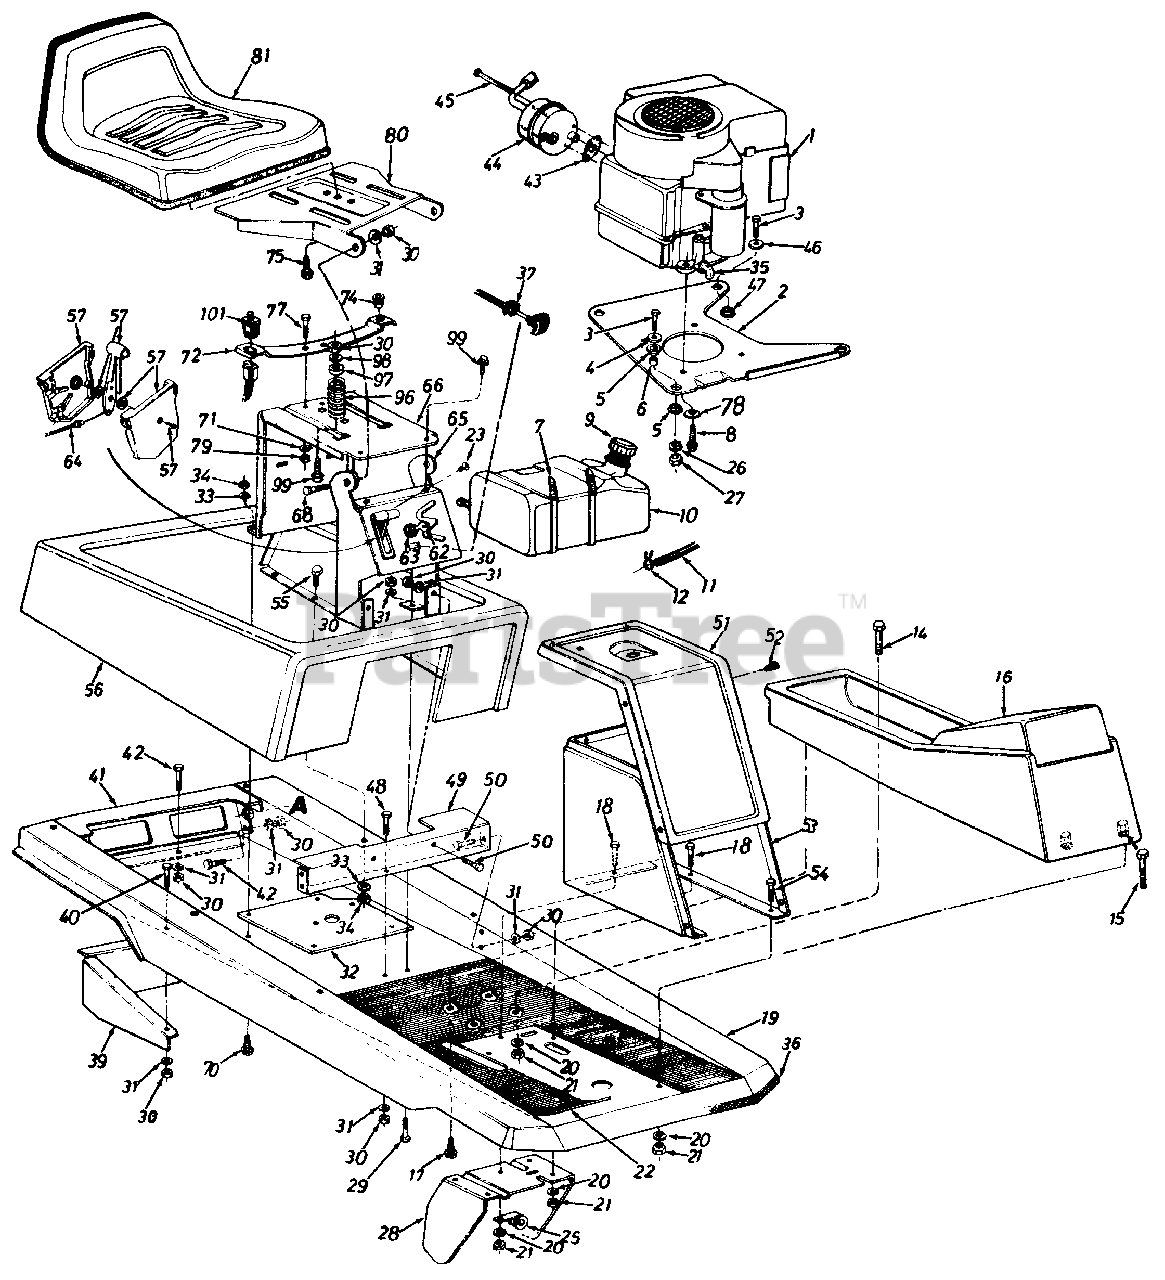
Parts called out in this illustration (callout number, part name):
1	Engine
4	Fl-Wash. .330" I.D. x 1.125" O.D.
5	Engine Mounting Grommet
6	Spacer .315" I.D. x .50" O.D. x .520" Lg.
7	Cable Tie 30.6 Lg.
8	Hex Wash. Hd. Self-Tap Scr. 3/8-16 x 1.25" Lg.
9	Gas Cap
10	Fuel Tank
11	Fuel Line - 26" Lg.
12	Hose Clamp - 1/2" O.D. Tube
14	Hex Bolt 5/16-18 x 1.75" Lg.
15	Hex Bolt 5/16-18 x 2" Lg.
16	Front Console
17	Plastite Scr. 5/16 x 1.25" Lg.
18	Hex Bolt 5/16-18 x .75" Lg.
19	Main Frame
20	L-Wash. 5/16" I.D.
21	Hex Nut 5/16-18 Thd.
22	Floor Mat
23	Truss Mach. Ab-Tap Scr. #10 x .50" Lg.
25	Clamp
26	L-Wash. 5/16" I.D.
27	Hex Nut 5/16-24 Thd.
28	Clutch-Brake Pedal Ass'y.
29	Hex Bolt 5/16-18 x .75" Lg
30	Hex Nut 5/16-18 Thd.
31	L-Wash. 5/16" I.D.
34	Hex Nut 1/4-20 Thd.
35	90ø Elbow Male To Female
36	Trim Strip (39" Req'd.)
37	Choke Control
43	Exhaust Gasket (8 H.P. B&S)
44	Muffler Ass'y. (8 H.P. B&S)
45	Shld. Bolt (8 H.P. B&S)
46	Fl-Wash. .330" I.D. x 1.25" O.D.
47	Flange Wash. .320" I.D. x .750" O.D.
49	Seat Support & Frame Brkt.
50	Hex Bolt 5/16-18 x .75" Lg.
55	Hex Bolt 1/4-20 x .50" Lg.
62	Ignition Key
63	Ignition Switch
64	Throttle Control Wire 35" Lg.
70	Hex Tap Scr. 1/4-20 x 1.0" Lg.
71	L-Wash. 5/16" I.D.
72	Seat Spring
74	Grommet
75	Hex Wash. Hd. Tap Scr. 3/8-16 x 3/4" Lg.
77	Hex Bolt 5/16-18 x .75" Lg.
78	Bell-Wash. .345" I.D. x .88" O.D.
79	Hex Cent. L-Nut 5/16-18 Thd.
80	Seat Pivot Bracket
81	Seat Ass'y. Comp.
96	Compression Spring 2.7" Lg.
97	Bushing
98	Fl-Wash. .344" I.D. x .875"
99	Hex Bolt 5/16-18 x 1" Lg. (Gr. 5)
101	Seat Switch
